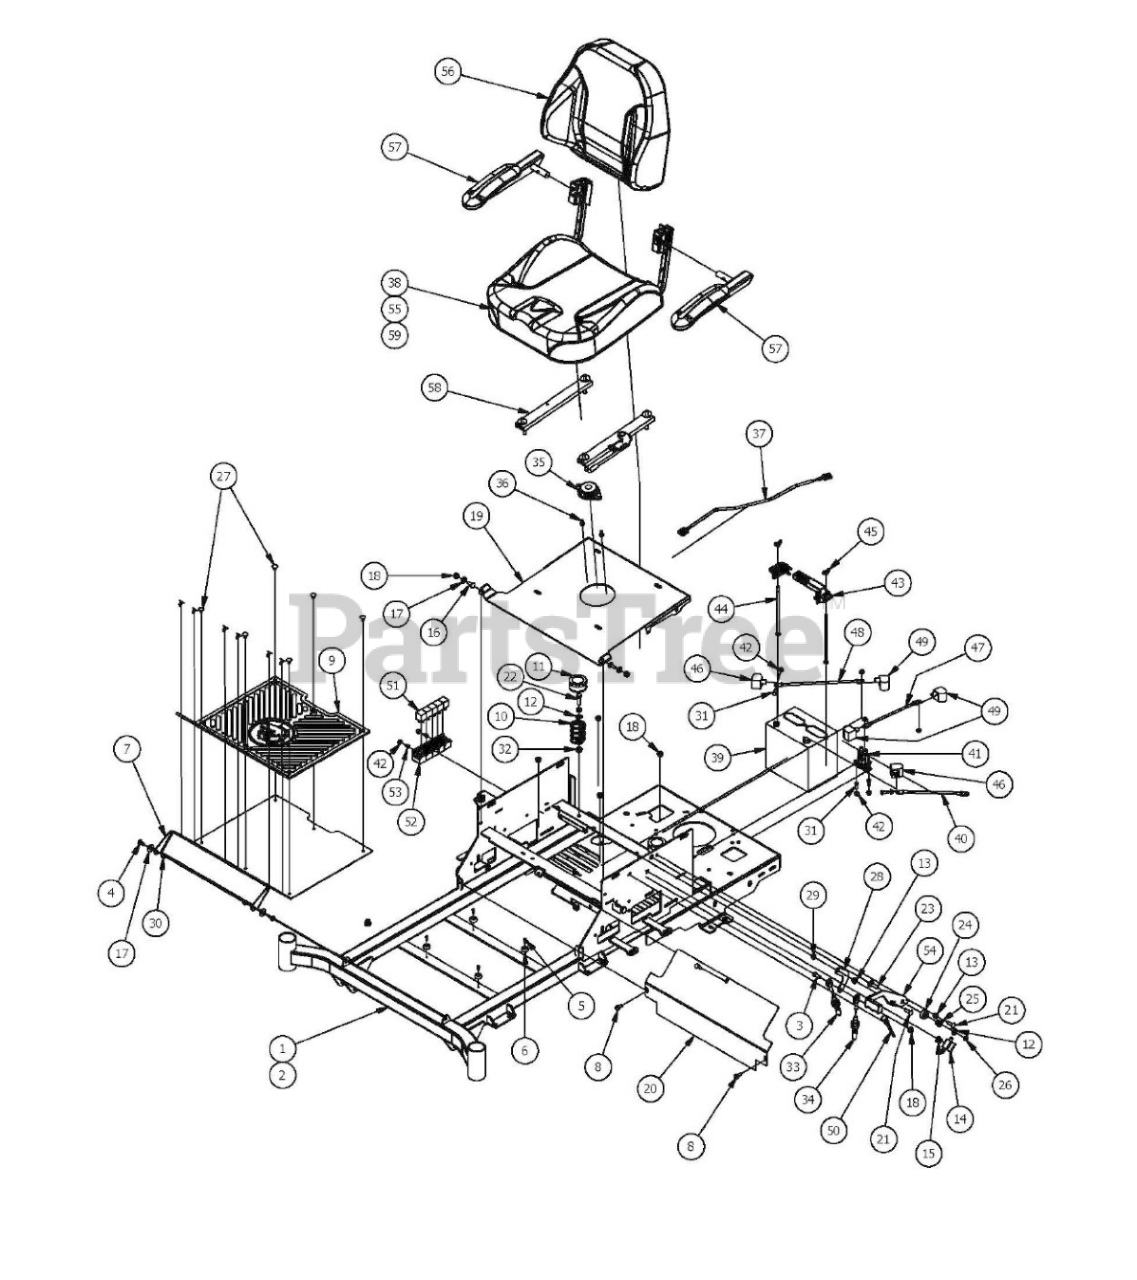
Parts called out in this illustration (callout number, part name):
1	ZT 48" Frame
2	ZT 54" and 60" Frame
3	5/16" x 3/4" Hex Bolt
4	1/4" x 3/4" Carriage Bolt
5	#10 x 1/2" Self Tapping Screw
6	Button Bumper
7	MZ/ZT 2017 Floorboard
8	5/16 x 3/4 washer head type F screw
9	2017 MZ/ZT Floor Mat
10	Seat Spring
11	Seat Spring Cap Cover
12	3/8" Flat Washer
13	5/16-18 Hex Flange Nut
14	Safety Switch
15	12-24x 1/2 HWH Bolt
16	5/16" x 7/8" Carriage Bolt
17	.360 ID Plastic Washer
18	5/16-18 Nylong Hange Nut
19	Seat Plate 2016
20	2017 ZT Cooler Cover
21	5/16" x 1" Carriage Bolt
22	3/8" x2" Hex Bolt
23	3/8" x 1 1/4" Carriage Bolt
24	2015 Brake Lever Spacer
25	Bronze Bushing SF-1220-8
26	3/8-16 Centerlock Half Nut
27	5/8" Christmas Tree Fastener
28	Brake Cable Adapter Bracket
29	5/16-18 Nylock Jam Nut 1/2 Nut
30	1/4-20 Nylon Insert flange Nut
31	1/4" x 3/4" Hex Bolt
32	3/8" Flange Nut
33	Brake Cable
34	Brake Cable
35	Seat Safety Switch
36	1/4-20x1/2 HWH Bolt Slot
37	Seat Switch Adapter
38	2017 ZT Seat
40	Ground Cable
42	1/4-20 Hex Flange Nuts Zinc w/Serrations
43	Battery Hold Down
44	1/4-20 X 8 Carriage Bolt
45	1/4" Wing Nut
46	Black Boot For Ground Cable
47	12 in red battery cable
48	24" Red Battery Cable
52	Wire Harness
53	1/4" x 1/2" BS C/S 18-8 SS
54	Brake Handle
55	ZT Seat Cushion
56	ZT Back Cushion
57	Arm Rest Pair
58	Seat Rails
